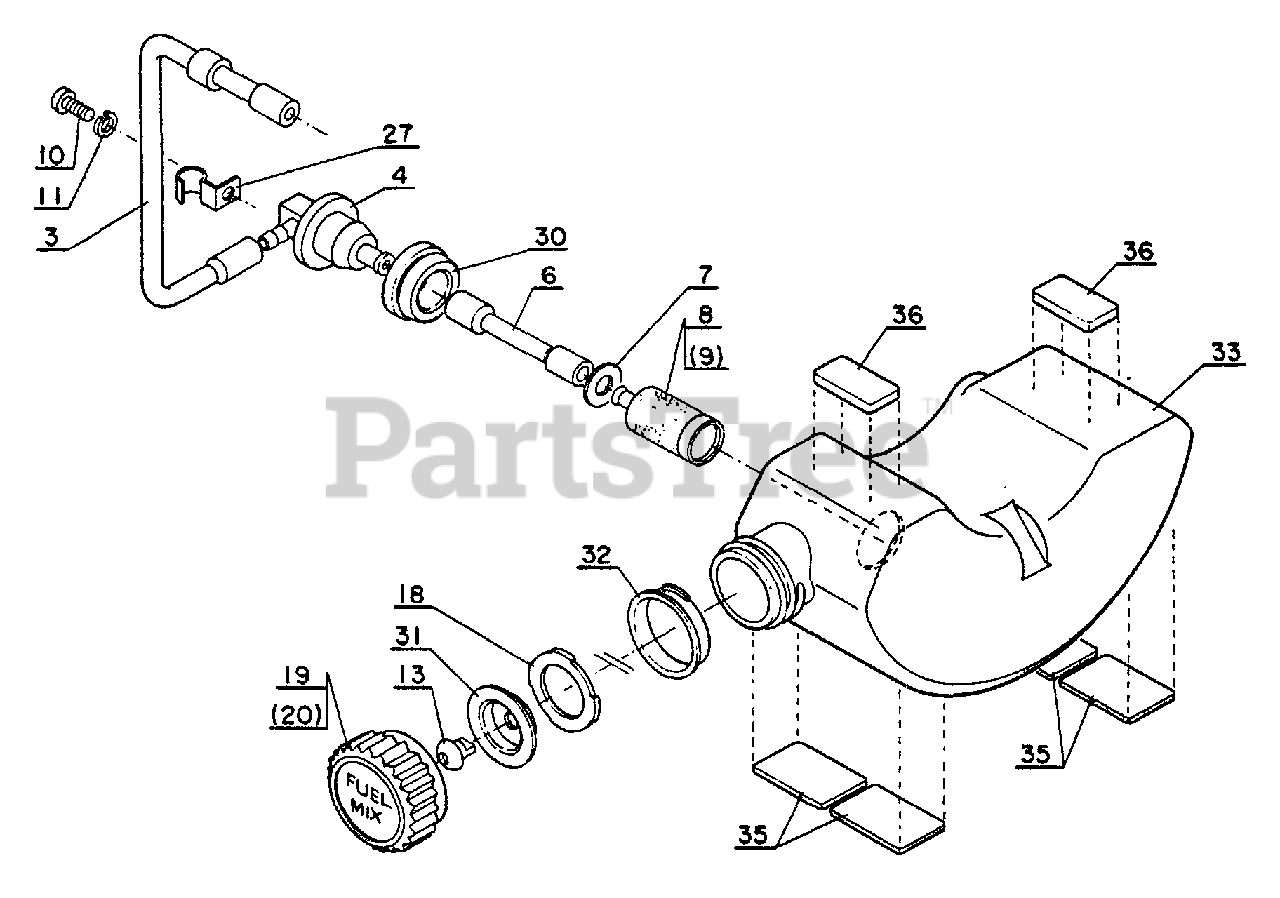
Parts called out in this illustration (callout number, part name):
3	PIPE, FUEL - OUTER
4	CONNECTOR, PIPE
6	PIPE, FUEL - INNER
7	WASHER - 6
8	FILTER, FUEL
10	SCREW - 4X12
11	LOCKWASHER - 4
18	GASKET, CAP
19	CAP
27	CLAMP
30	GROMMET
31	HOLDER, VENT
32	GASKET
33	TANK, FUEL
35	CUSHION - LOWER
36	CUSHION - UPPER
